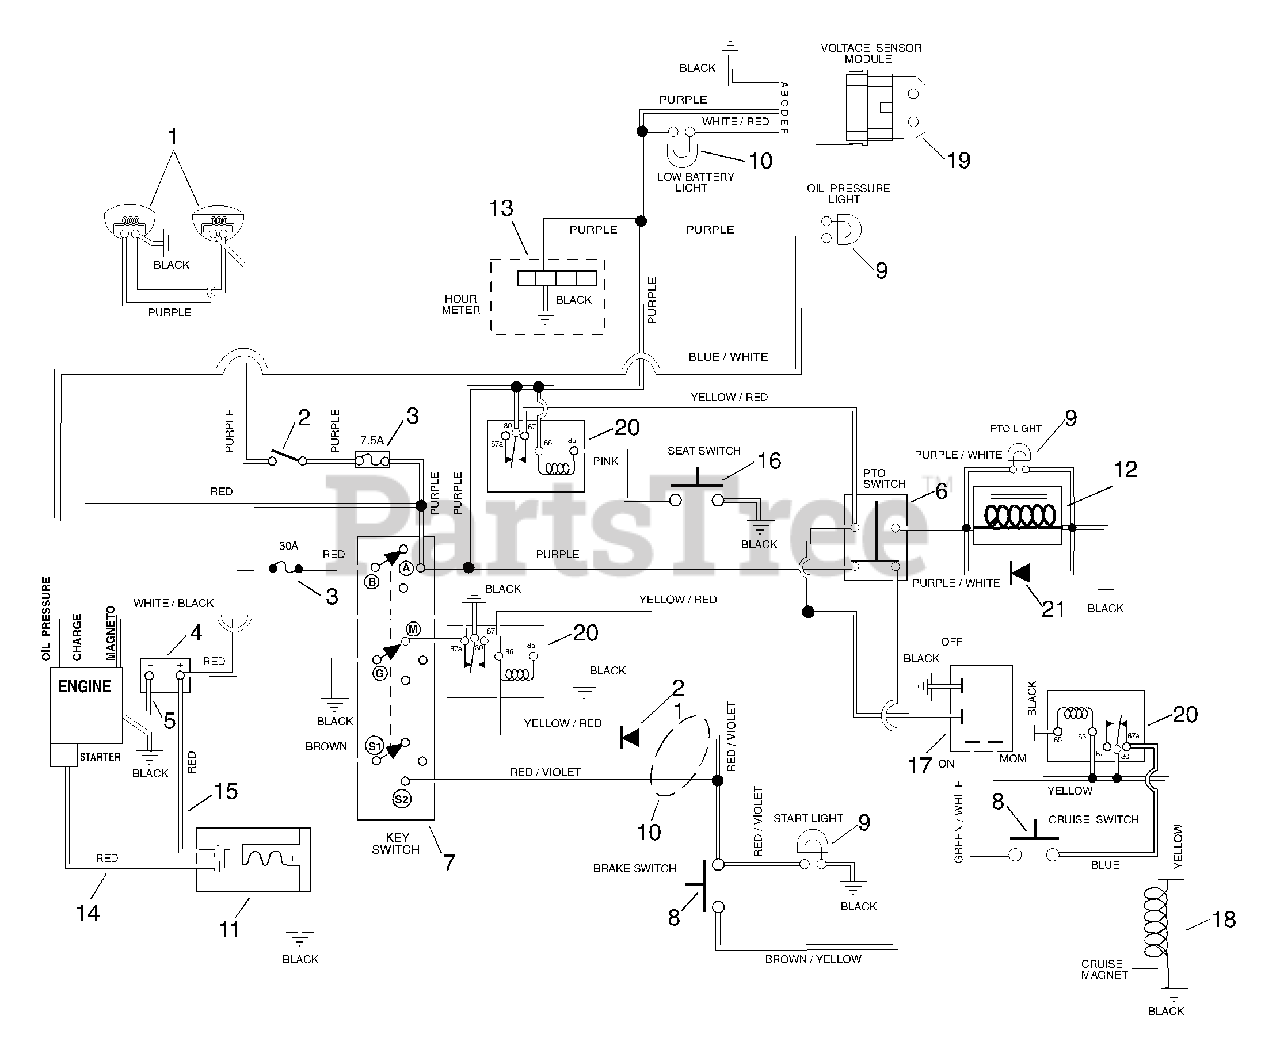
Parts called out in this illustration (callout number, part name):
1	HEADLIGHT- RH
1	HEADLIGHT- LH
2	SWITCH - LIGHT
3	7.5 AMP Fuse
3	30 AMP Fuse
4	BATTERY W/TUBE
5	GROUND CABLE .31X22.00X.31
6	PTO KNOB/ SWITCH ASSY
7	KEY SWITCH
8	SWITCH- SINGLE POLE N.O.
9	#194 Bulb
10	HARNESS, WIRING - 1540 KOHLER
10	HARNESS, WIRING - 1548 KOHLER
11	SOLENOID
12	ELECTRIC CLUTCH/BRAKE (3.4AMP)
12	CLUTCH, ELECTRIC - WARNER
13	HOURMETER KIT- SIERRA
14	START CABLE 22"
15	STARTER CABLE 6.75"
16	SWITCH- SEAT
17	SWITCH - CRUISE
19	MODULE - VOLTAGE SENSOR
20	RELAY
21	MOLDED DIODE PLUG 1 AMP
